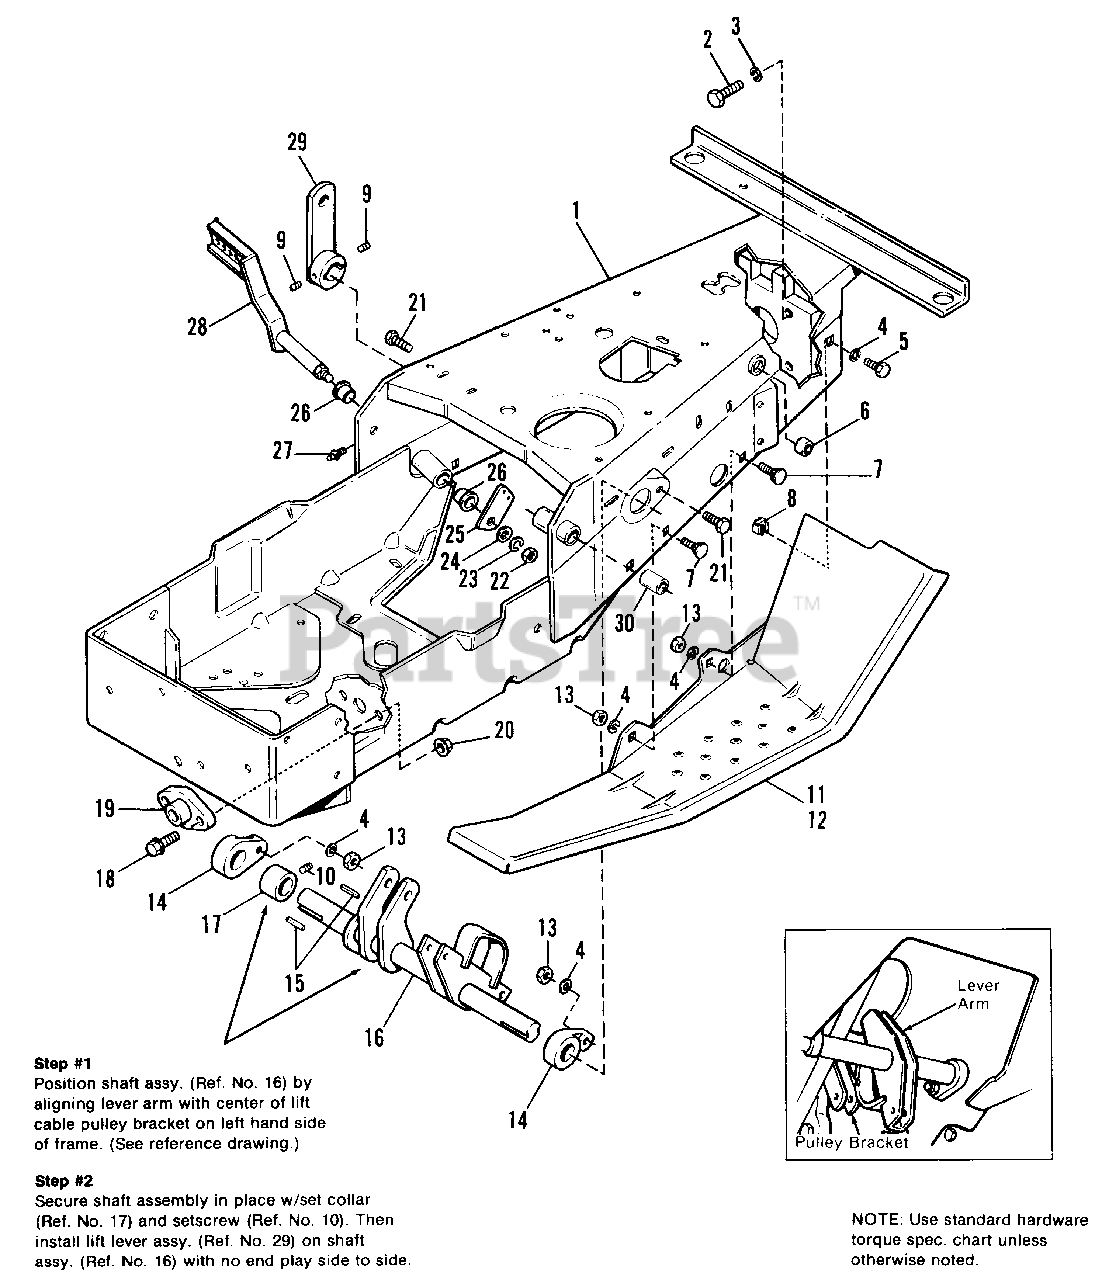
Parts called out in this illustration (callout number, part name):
1	FRAME ASSY., w/Bushings
2	CAPSCREW, Hex Hd., 7/16-14 x 1-1/2
3	LOCKWASHER, 7/16
4	LOCKWASHER 5/16
5	CAPSCREW, Hex Hd., 5/16-18 x 3/4
7	BOLT, Carriage, 5/16-18 x 3/4
8	NUT, Speed, 5/16-18
9	SETSCREW, 5/16-18 x 14
10	SETSCREW, 5/16-18 x 3/8
11	FOOTREST, LH
12	FOOTREST, RH.
13	NUT, Hex, Full, 5/16-18
14	BEARING, Lift Lever
16	SHAFT ASSY., Lift
17	COLLAR, Set
18	SCREW, Hex, Whiz, Flange, 3/8-16 x 1-1/4
19	BEARING, Pivot
20	LOCKNUT, Hex, Flange, 3/8-16
21	CAPSCREW, Hex Hd., 5/16-18 x 1-3/4
22	NUT, Hex, Full, 3/8-16
23	LOCKWASHER, 3/8
24	WASHER, Plain, 3/8
25	ARM, Foot Pedal
27	FITTING, Grease
28	PEDAL ASSY., Foot
29	LEVER ASSY., RH
30	BEARING, Interim Pinion
